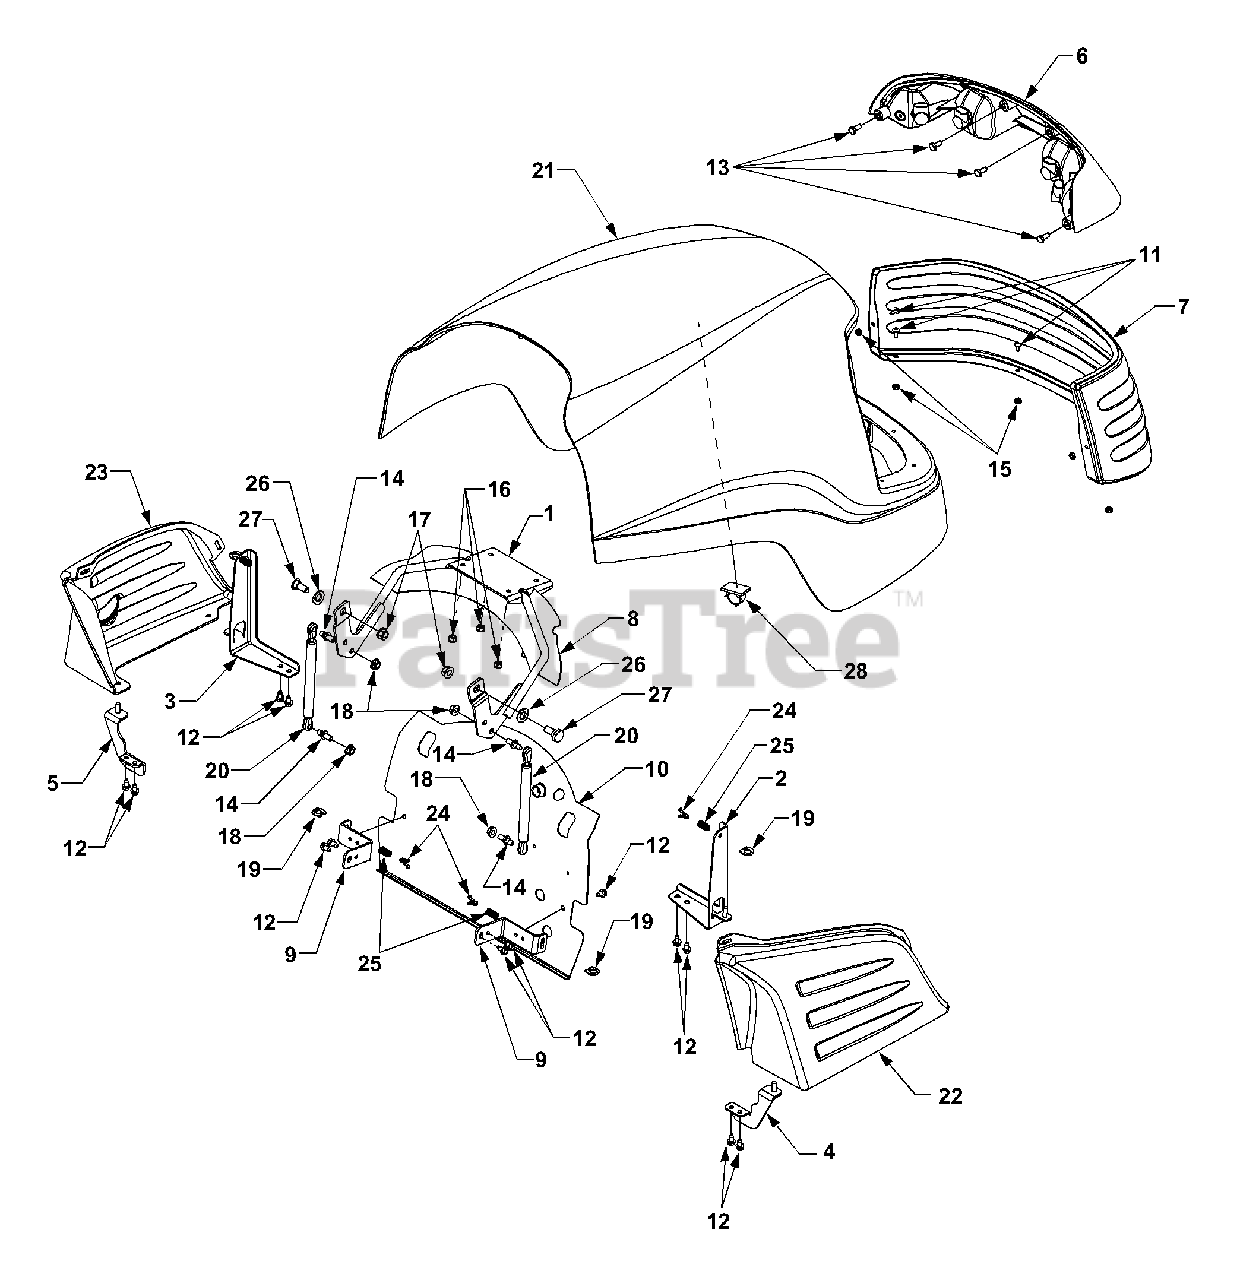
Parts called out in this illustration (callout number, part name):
1	Hinge Assembly, Hood
2	Bracket, Side Panel Mtg. RH
3	Bracket, Side Panel Mtg. LH
4	Bracket, Side Panel Mtg. RH Rear
5	Bracket, Side Panel Mtg. LH Rear
6	Headlight Assembly
9	Bracket, Panel Mtg.
10	Shield, Lower Heat
11	Screw, Truss Hd, 10-24 x .5
12	Screw, Hex Wash Hd Tapp 1/4-20 x .5
13	Screw, Hex Cap, 1/4-20 x .62 GR5
14	Stud, Cylinder, 5/16-18 Thrd
15	Nut, Hex Sems, 10-24
16	Nut, Hex Nylon Insert Lock, 1/4-20
17	Nut, Hex Flange Lock, 3/8-16
18	Nut, Hex Flange Lock, 5/16-18
19	Latch, 1/4 Turn Panel
20	Cylinder, Gas Spring
21	Hood, Service Kit
21	Hood
22	Panel, Side RH
23	Panel, Side LH
24	Clip, Spring
25	Spring, Compression
26	Washer, Flat, .510 x .1.0 x .060
27	Screw, Shoulder, .5 x .27 Lg 3/8-16
28	Clip, Retaining
